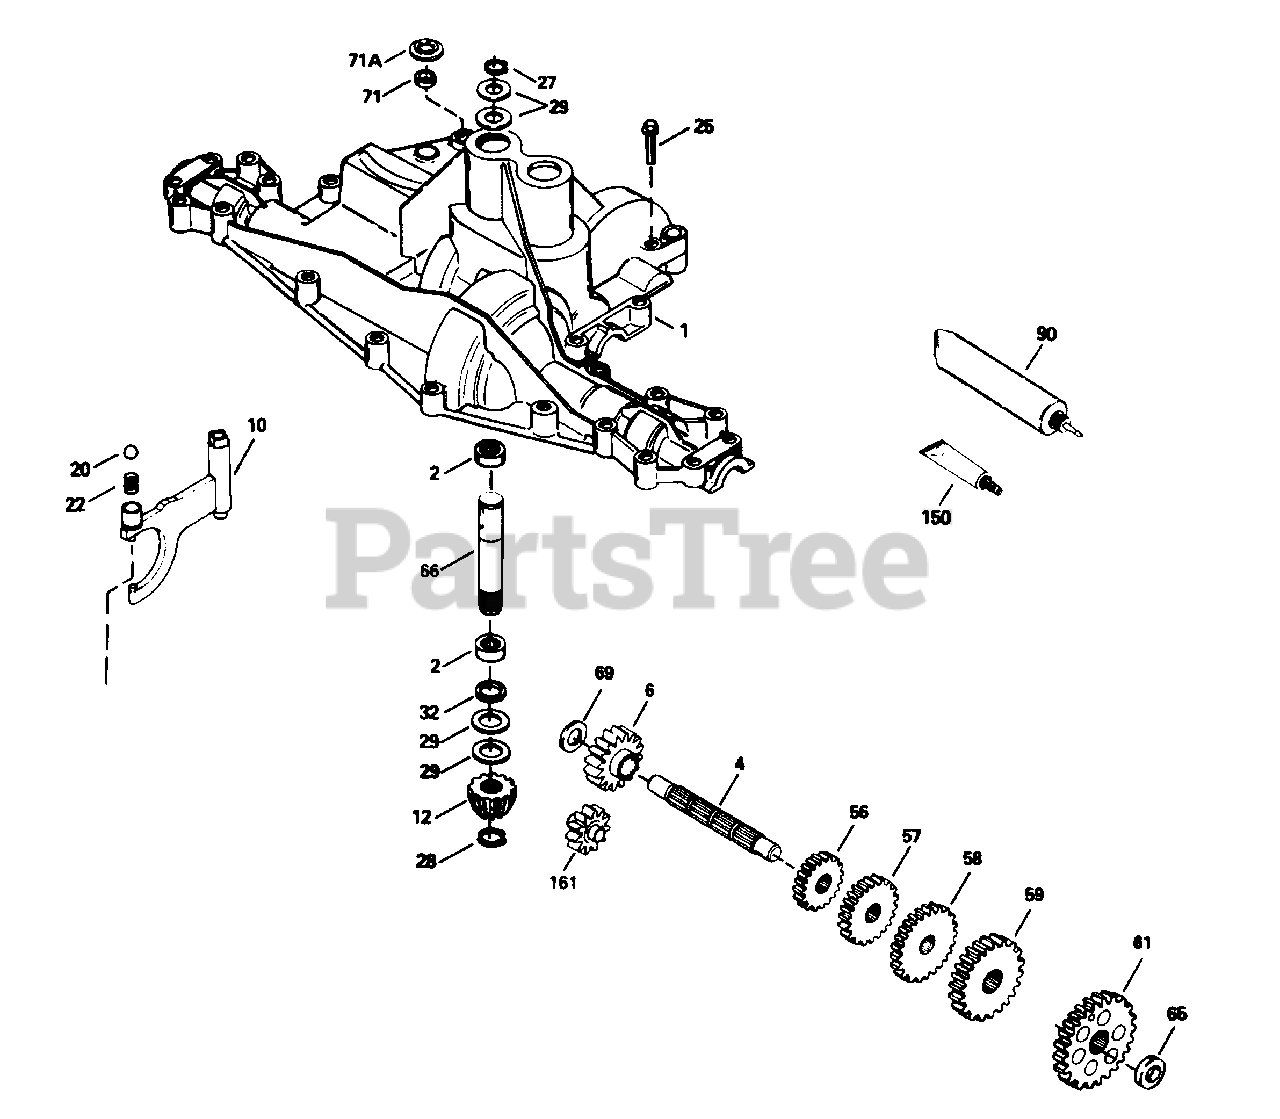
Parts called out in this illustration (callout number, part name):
1	Transaxle Cover
4	Countershaft
6	Spur Gear (16 Teeth)
10	Shift Rod & Fork
12	Bevel Pinion (14 Teeth)
20	Ball (3/8" dia.)
27	Retaining Ring
28	Retaining Ring
56	Spur Gear (15 Teeth)
57	Spur Gear (23 Teeth)
58	Spur Gear (21 Teeth)
59	Spur Gear (30 Teeth)
61	Spur Gear (34 Teeth)
66	Input Shaft (3.522" lg.)
69	Thrust Washer
71	Square Cut Ring
71A	Pushnut
90	Grease (32 oz. btl. Bentonite grease)
150	Gasket Eliminator (Loctite #515)
161	Reverse Idler Assembly
